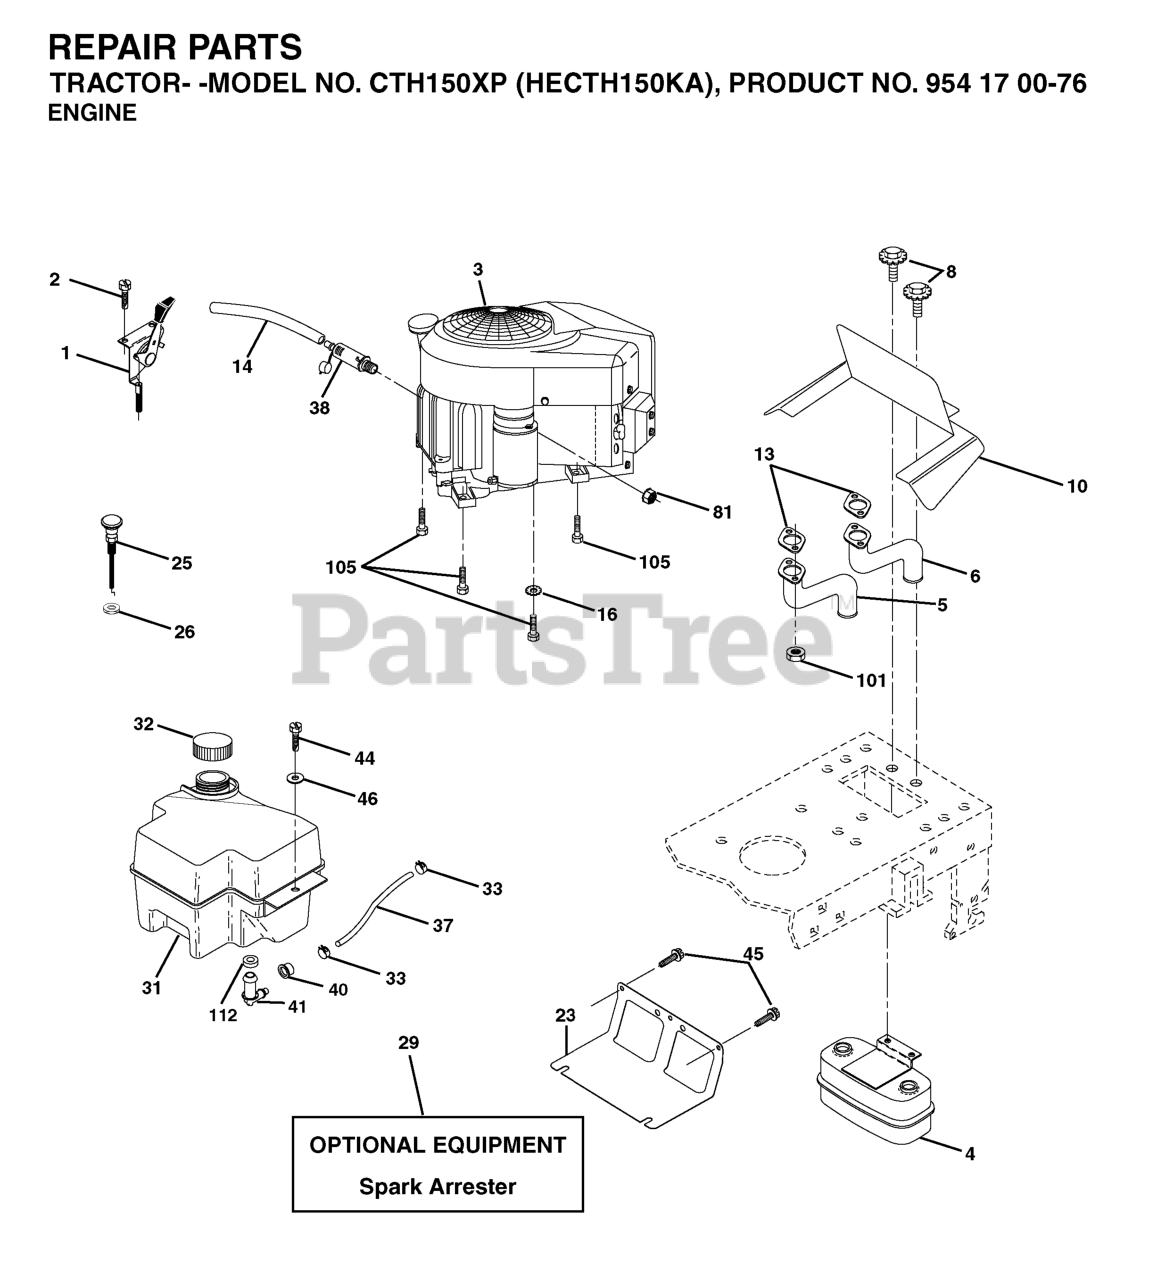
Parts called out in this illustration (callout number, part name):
1	CONTROL, THROTTLE
2	SCREW
4	MUFFLER.TWIN.CYL.LOW.TONE
5	EXHAUST TUBE LH KAWI
6	EXHAUST TUBE RH KAWI
8	BOLT.5/16-18UNCX3/4 W/SEMS.BLK
10	RP SHIELD HEAT MUFFLER
14	TUBE, DRAIN OIL ASM.
16	LOCKWASHER
23	SHIELD.BROWNING.DBR.GUARD
25	CHOKE CONTROL
26	Nut Keps 3/8 - 24 UNF
29	KIT.SPARK ARRESTOR 794945 B&S
31	GAS TANK 2GAL
32	FUEL CAP
33	HOSE CLAMP
37	LINE.FUEL.20
40	BUSHING.SNAP.NYL.BLK.
41	STEM FUEL TANK
44	SCREW HEXWSHR 1/4-20X3/4
45	SCREW, 3/8-16X3/4
81	NUT
101	FLANGE NUT
105	SCREW 3/8-16X1
112	BUSHING OUTLET T
